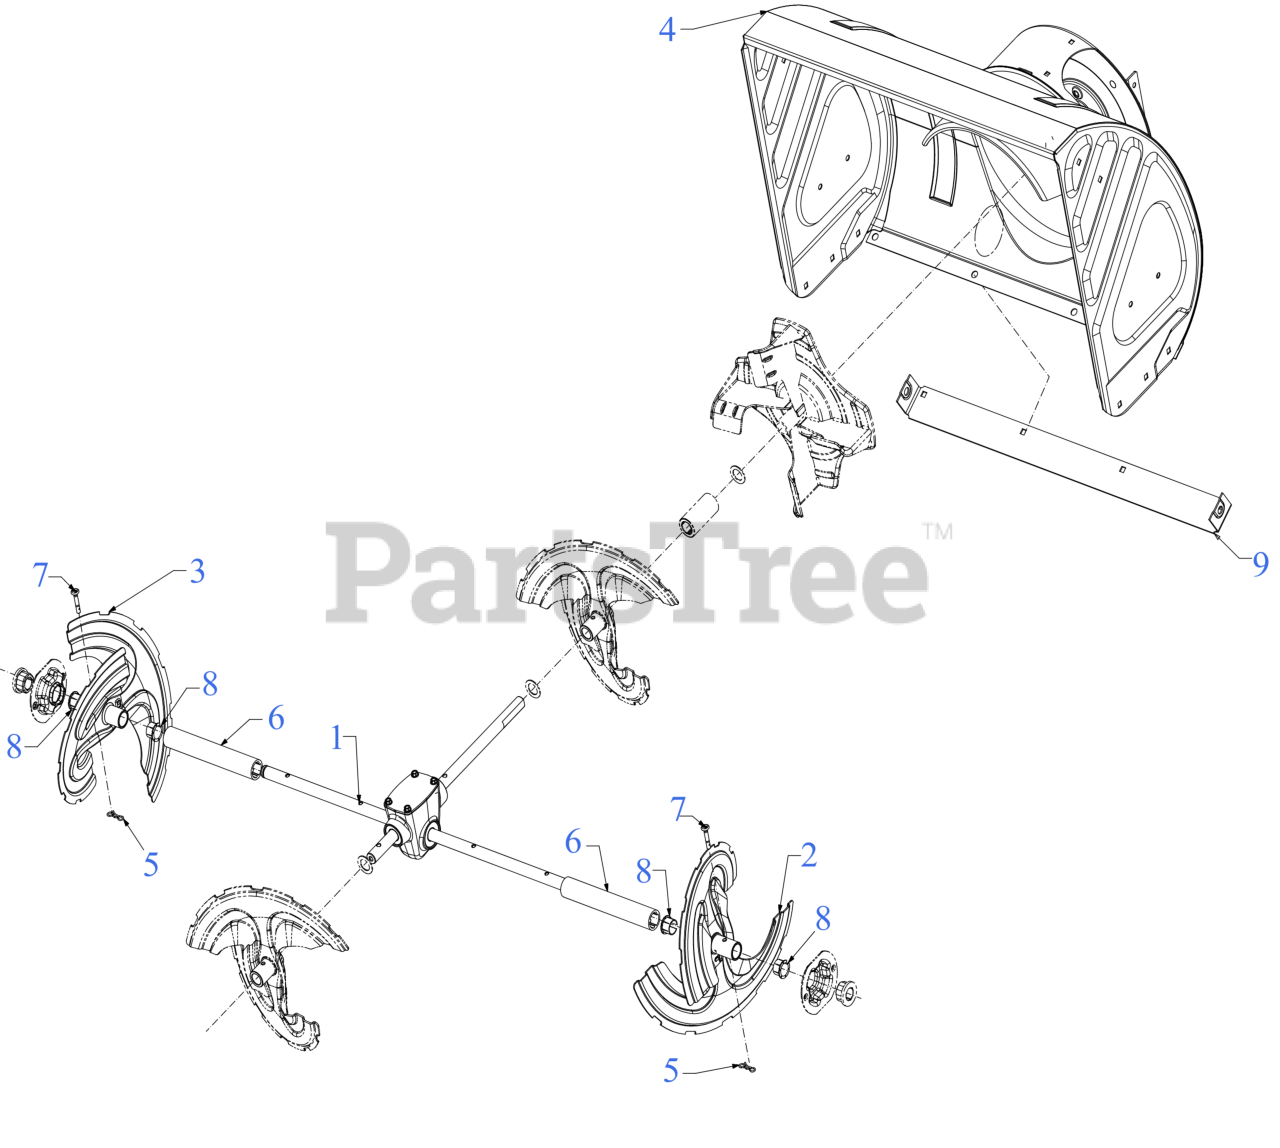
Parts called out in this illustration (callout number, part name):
1	GEARBOX ASSEMBLY 28"
5	BOW TIE COTTER PIN 1/4-5/16
7	SHEAR PIN (.25 x 1.50)
8	FLANGE BUSHING
